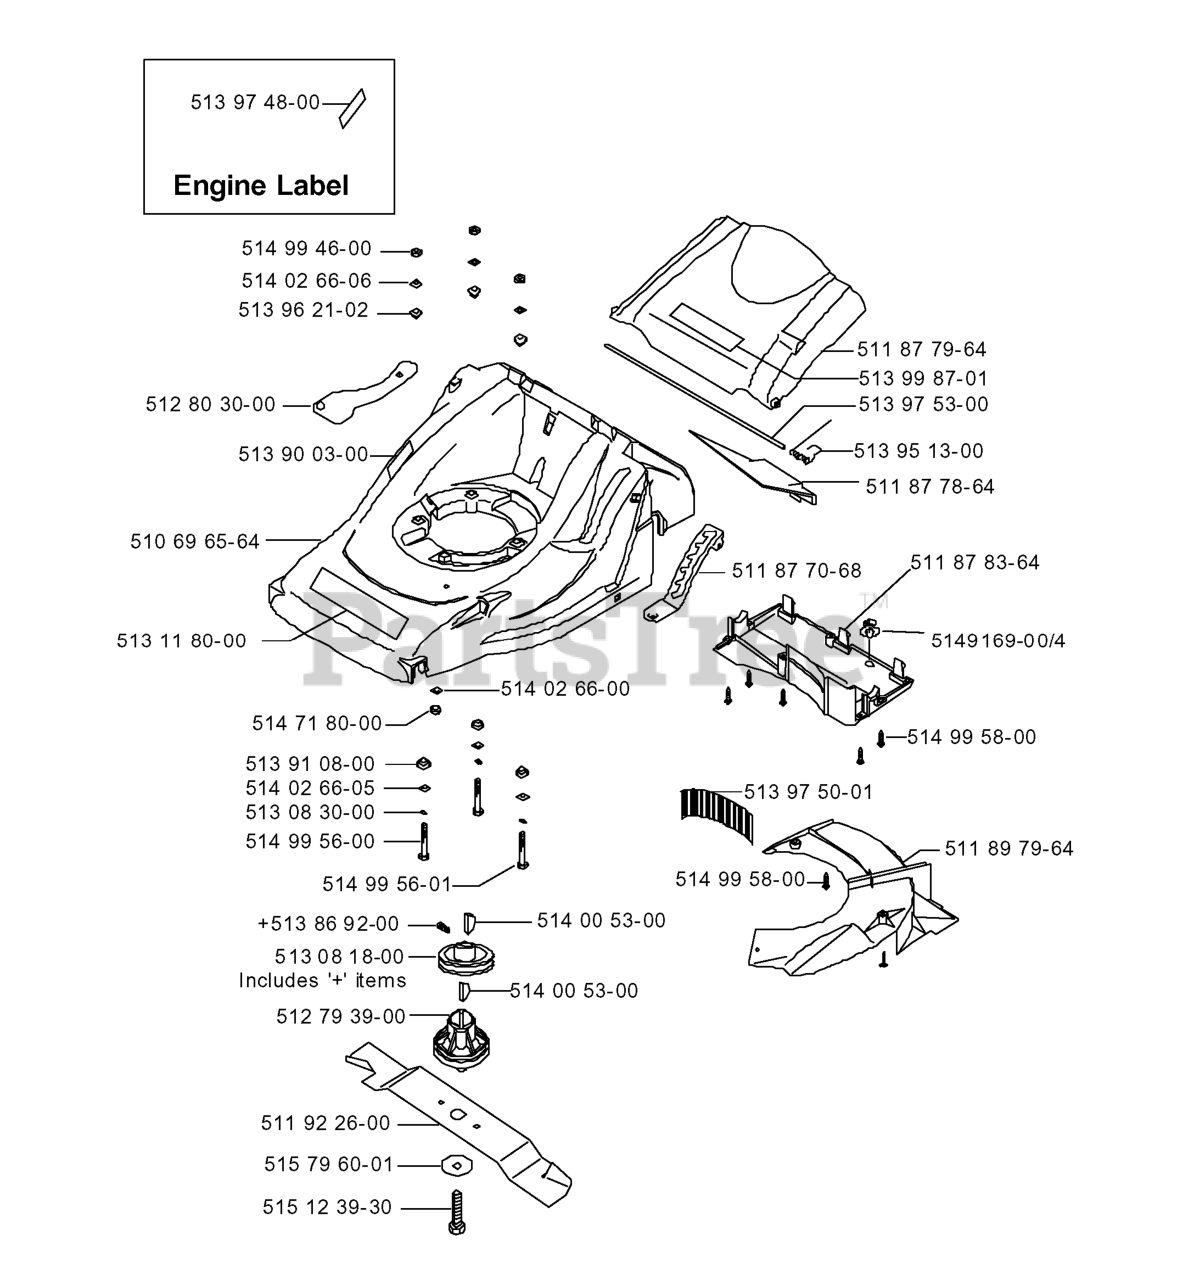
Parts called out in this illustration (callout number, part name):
2	RP BOLT 5/16-18 X3/4 ZN/YEL GR
5	RETAINER-SPRNG RB
6	BAR.SWAY.92.CRD
8	BOLT.3/8-24X1.25 GR8
9	LOCKWASHER
13	SHAFT ASM VENT
14	HOUSING.MANDREL.VENTED (MACHD)
17	BOLT.3/8-14X1.25
18	BOLT
19	BOLT SHD 5/16-18
20	BOLT.3/8-24X1.25GR8. LHTHRD
21	LOCKNUT
26	SUPPORT
30	SCREW, WASHER HEAD
31	WASHER.SPACER.MANDREL
33	NUT.FLANGE.LOCK.TOP
36	PULLEY.IDLER.4.25
41	NUT LOCK FLG 3/8-16 UNC
45	COVER.MANDREL.RH.CRD
46	SCREW.1/4-20X5/8
55	ARM.IDLER.92 CRD.2006
56	SPACER.RETAINER.MOWER
61	SPRING
68	BELT.DRIVE.92CM.CRD.2006
69	SHAFT.ASM.W/LWR.BRG.RH.THREAD
84	KEEPER, BELT IDLER
116	BOLT.SHOULDER.3/8-16X3-5/8.
117	RP WHEEL. GUAGE RALLY
118	NUT LOCK FLG 3/8-16 UNC
119	WASHER
124	BOLT.3/8-16X1.50
130	BOLT.CARR.SQNK.5/16-18UNC.X3/4
131	CHUTE BAGGER
